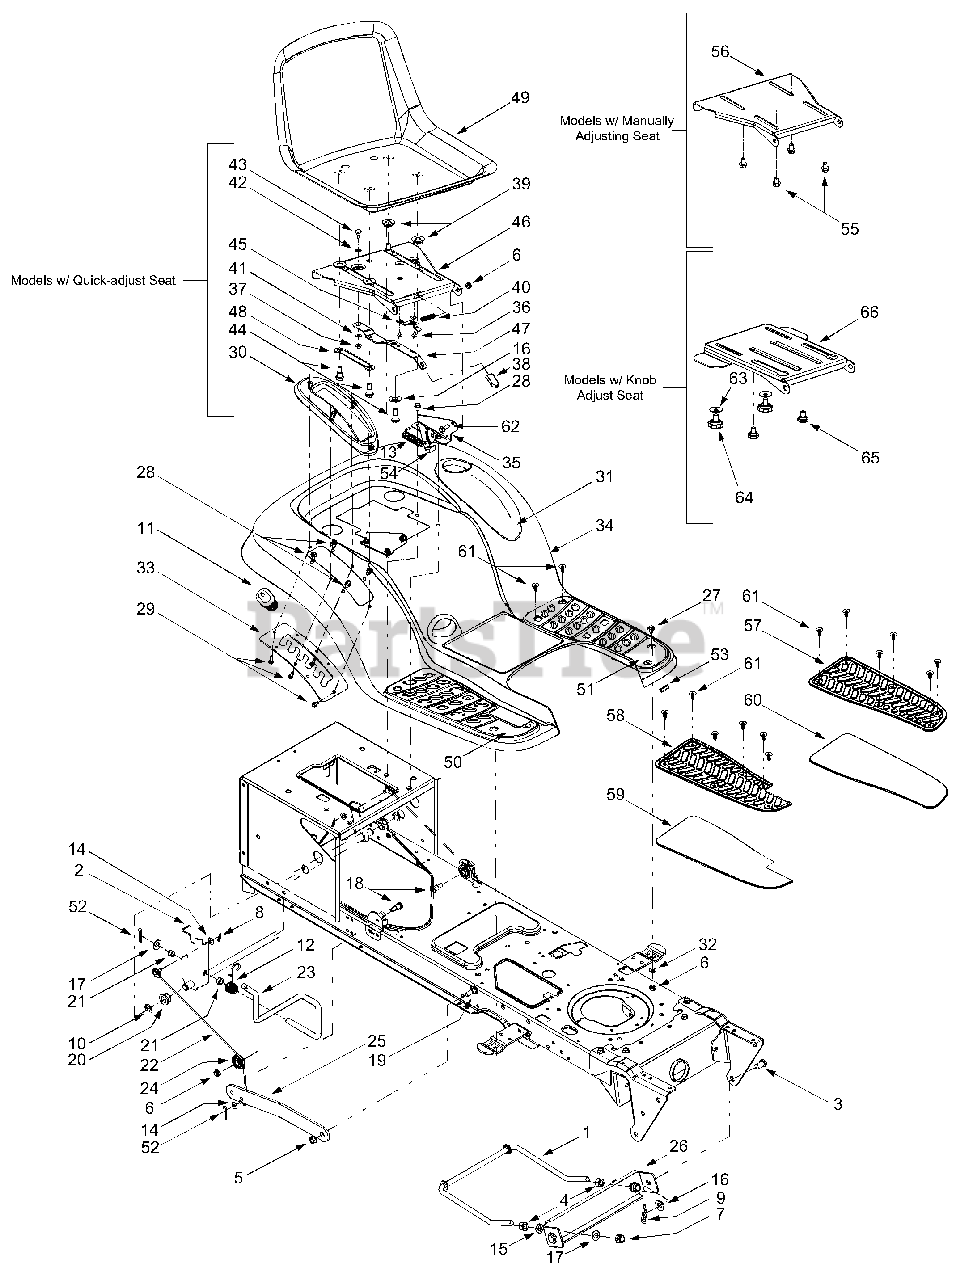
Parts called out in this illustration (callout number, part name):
1	Deck Stabilizer Rod
2	Lift Shaft Assembly
3	Clevis Pin, .5 x .78
4	Hex Nut, 1/2-13
5	Flange Lock Nut, 3/8-16
6	Flange Lock Nut, 5/16-18
7	Hex Nut, 1/2-13
8	Internal Cotter Pin
9	Internal Cotter Pin
10	E-Ring
11	Handle Grip
12	Torsion Spring
13	Extension Spring
14	Flat Washer, 5/16
15	Lock Washer, 1/2
16	Flat Washer, .31 x 1.062 x .134
17	Flat Washer, .51 x 1.12 x .06
18	Hex Cap Screw, 5/16-18 x .62
19	Shoulder Screw, 3/8-16
20	Hex Flange Bearing
21	Snap Flange Bearing
22	Lift Cable, 16.16
23	Lift Handle
24	Roller Pulley
27	Carriage Bolt, 5/16 x .62
28	AB Screw, 5/16-12 x .75
29	Self-tapping Screw, 1/4-15 x .75
30	Lift Lever Cover
31	Cover w/ Cup Holder
32	Flat Washer, .349 x 1.0 x .063
36	Screw, #10-16 x .375
37	Hex Flange Lock Nut, 1/4-20
38	Seat Adjuster Grip
39	Spacer
40	Compression Spring, .41 x 1.5
41	Spring Washer, .265 x .562 x .025
42	Flat Washer, .344 x .62 x .03
43	Shoulder Screw, .340 x .285,1/4-20
44	Shoulder Screw
45	Seat Stop
48	Seat Adjustment Selector
49	Seat, Yellow
50	RH Foot Pad
51	LH Foot Pad
52	Cotter Pin
53	Trim Strip
54	Seat Lift Bracket
55	Fender Clips
56	Fender Flare RH
57	Fender Flare LH
59	Carriage Screw 1/4-20 x 1.0"
